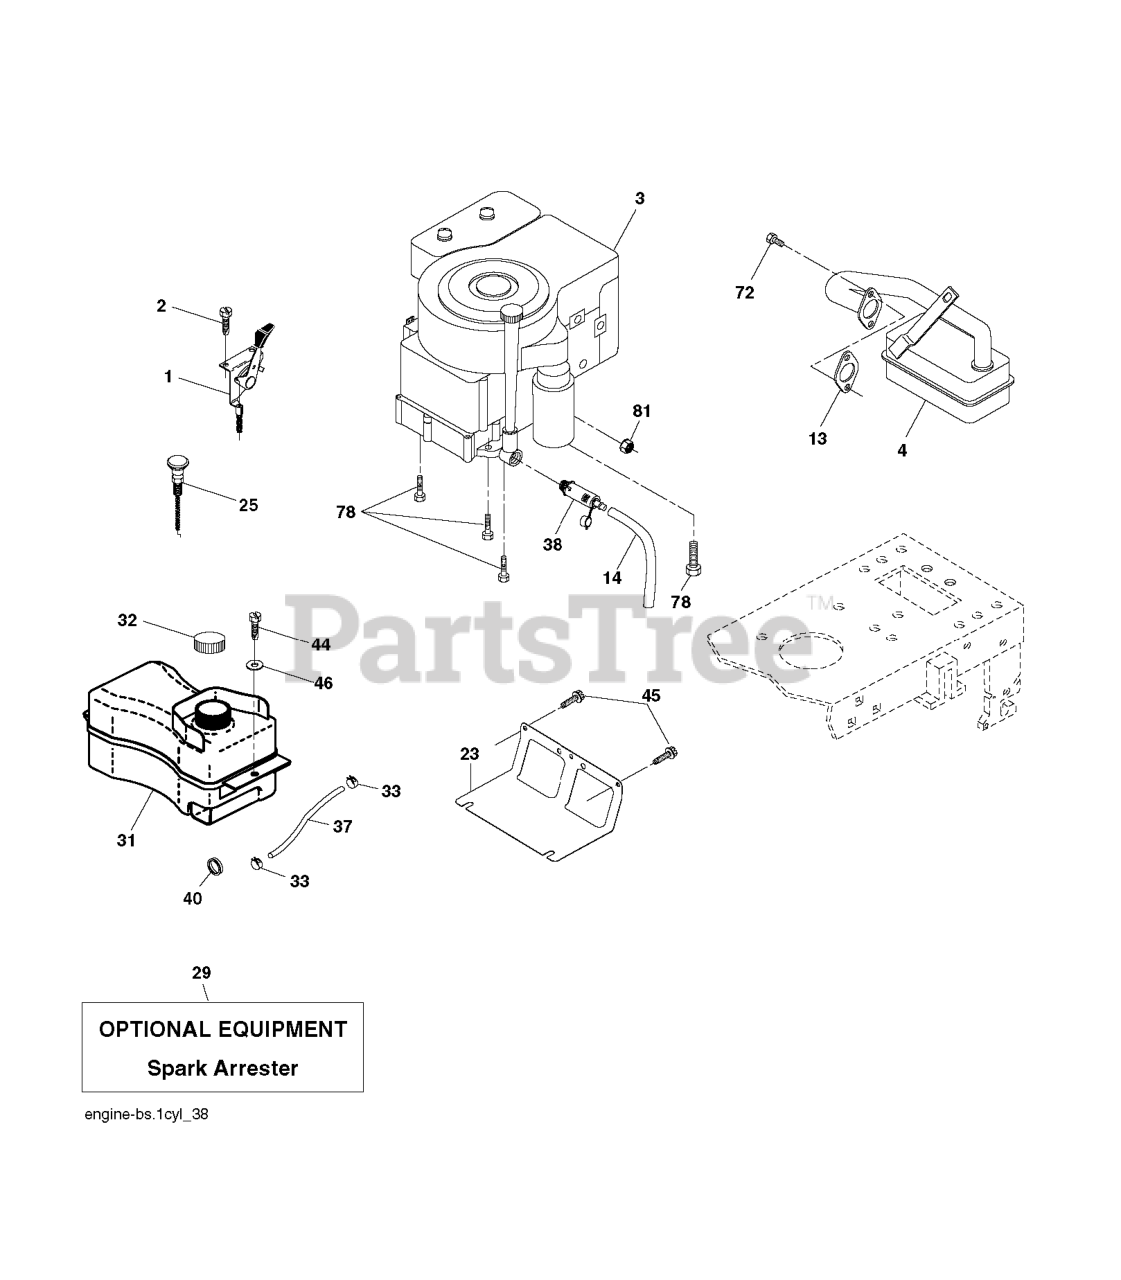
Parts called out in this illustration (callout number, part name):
1	CONTROL.THROTTLE/CHOKE.BLACK
2	SCREW
4	MUFFLER.B&S.MODEL.21.11HP.OHV
13	REPL BY 532 27 22-93
14	TUBE, DRAIN OIL ASM.
23	SHIELD.BROWNING.DBR.GUARD
25	KNOB.ERGO.EXTENDED.RED (1 2)
29	KIT.SPARK ARRESTOR 794945 B&S
32	FUEL CAP
33	HOSE CLAMP
37	LINE.FUEL.20
38	PLUG DRAIN OIL EASY
40	BUSHING.SNAP.NYL.BLK.
44	SCREW HEXWSHR 1/4-20X3/4
45	SCREW, 3/8-16X3/4
72	SCREW.SOCKET HD.5/16-1
78	SCREW.3/8-16
81	NUT
